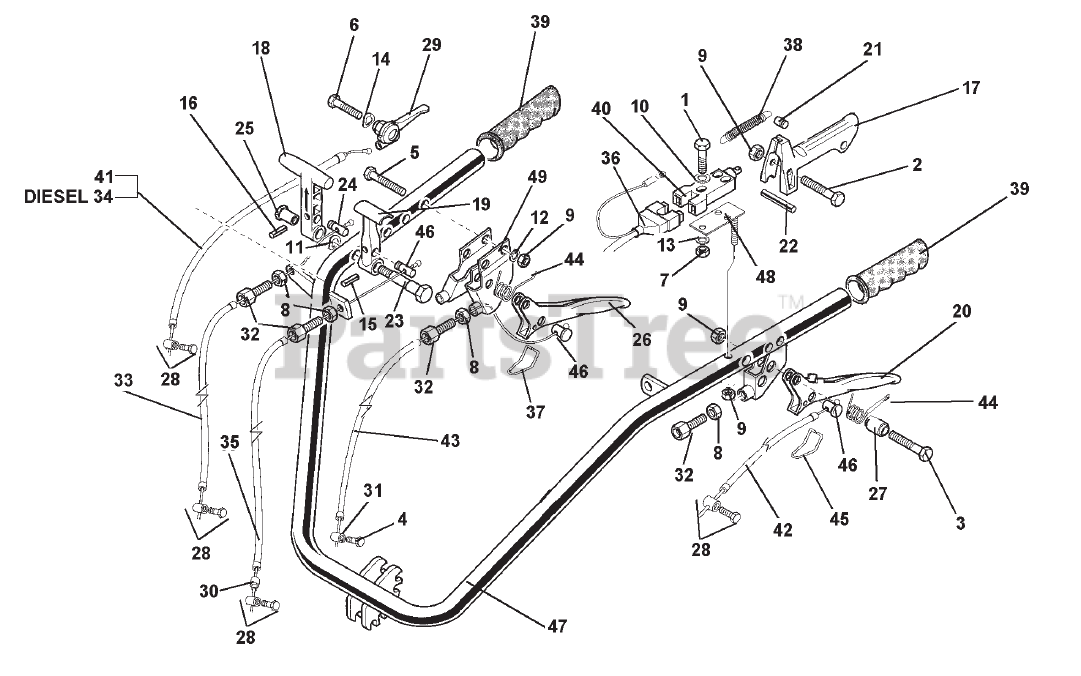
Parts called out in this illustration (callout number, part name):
1	SCREW TE M4X25
2	SCREW TE M6X45
3	SCREW M6X25
4	SCREW TE M6X16
5	SCREW M6X40
6	SCREW TE M8X40
9	NUT, SELF LOCKING M6
10	FLAT WASHER 4,3
12	WASHER, LOCK 6,4
13	LOCK WASHER B 4,3
14	WASHER, LOCK 8,4
15	PIN, LOCKING 4X20
16	PIN, LOCKING M4X20
17	MOTOR STOP LEVER
18	REVERSER LEVER
19	LEVER DIFFERENTIAL LOCKING
20	CLUTCH LEVER
22	LEVER STOP FOR MOTOR STOP
24	DRILLED PIN
25	DRILLED PIN
27	LEVER SPACER
28	CLAMP, CABLE
29	LEVER, ACCELERATOR
31	PIN, CABLE CLAMP
32	SCREW, ADJUSTING M8
33	CABLE, CLUTCH
34	THROTTLE CABLE, DIESEL
35	CABLE, DIFFERENTIAL LOCK OUT
36	SWITCH WIRING HARNESS
40	STOP SWITCH
41	THROTTLE CABLE
42	CLUTCH CABLE
43	CABLE, CLUTCH
44	LEVER SPRING
47	HANDLE ASSEMBLY
48	SWITCH PLATE
49	COUPLING FOR DOUBLE LEVER
